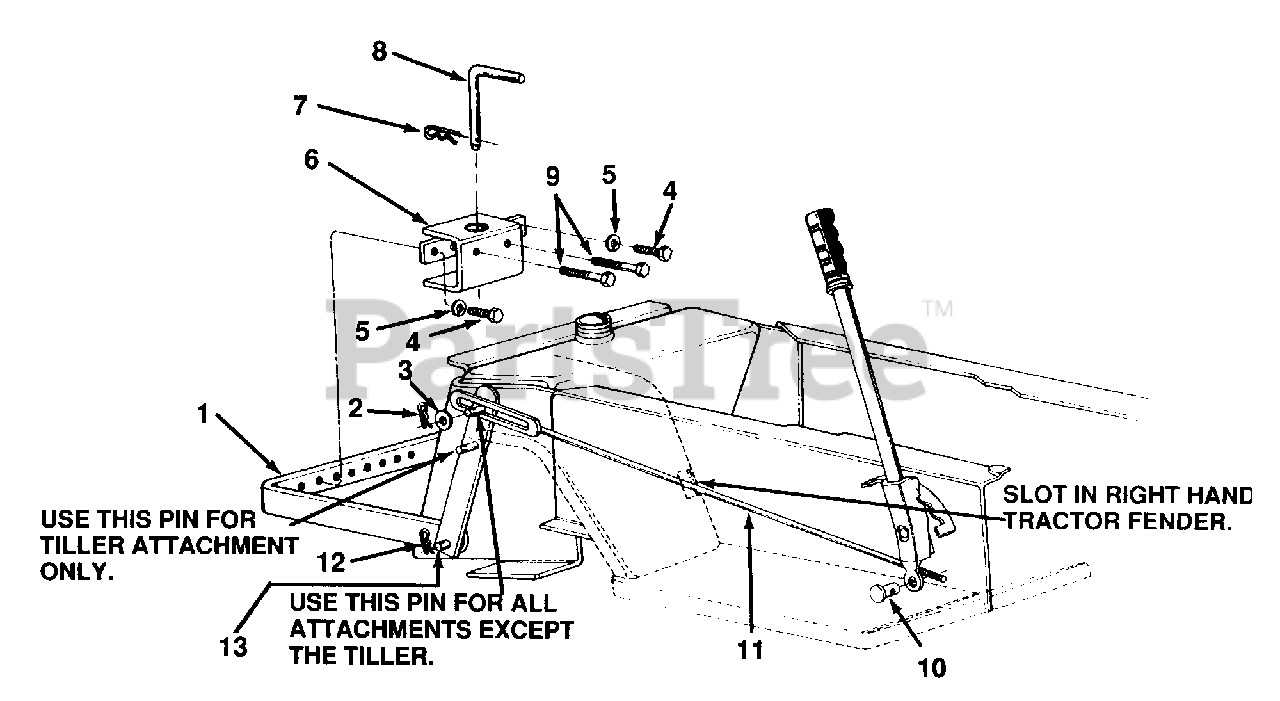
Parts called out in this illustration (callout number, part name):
3	Fl-Wash. 1/2" I.D.
4	Hex Bolt 1/2-13 x 1.0" Lg.
5	L-Wash. 1/2" I.D.
9	Hex Bolt 1/2-13 x 3.0" Lg.
10	Adjustment Ferrule
